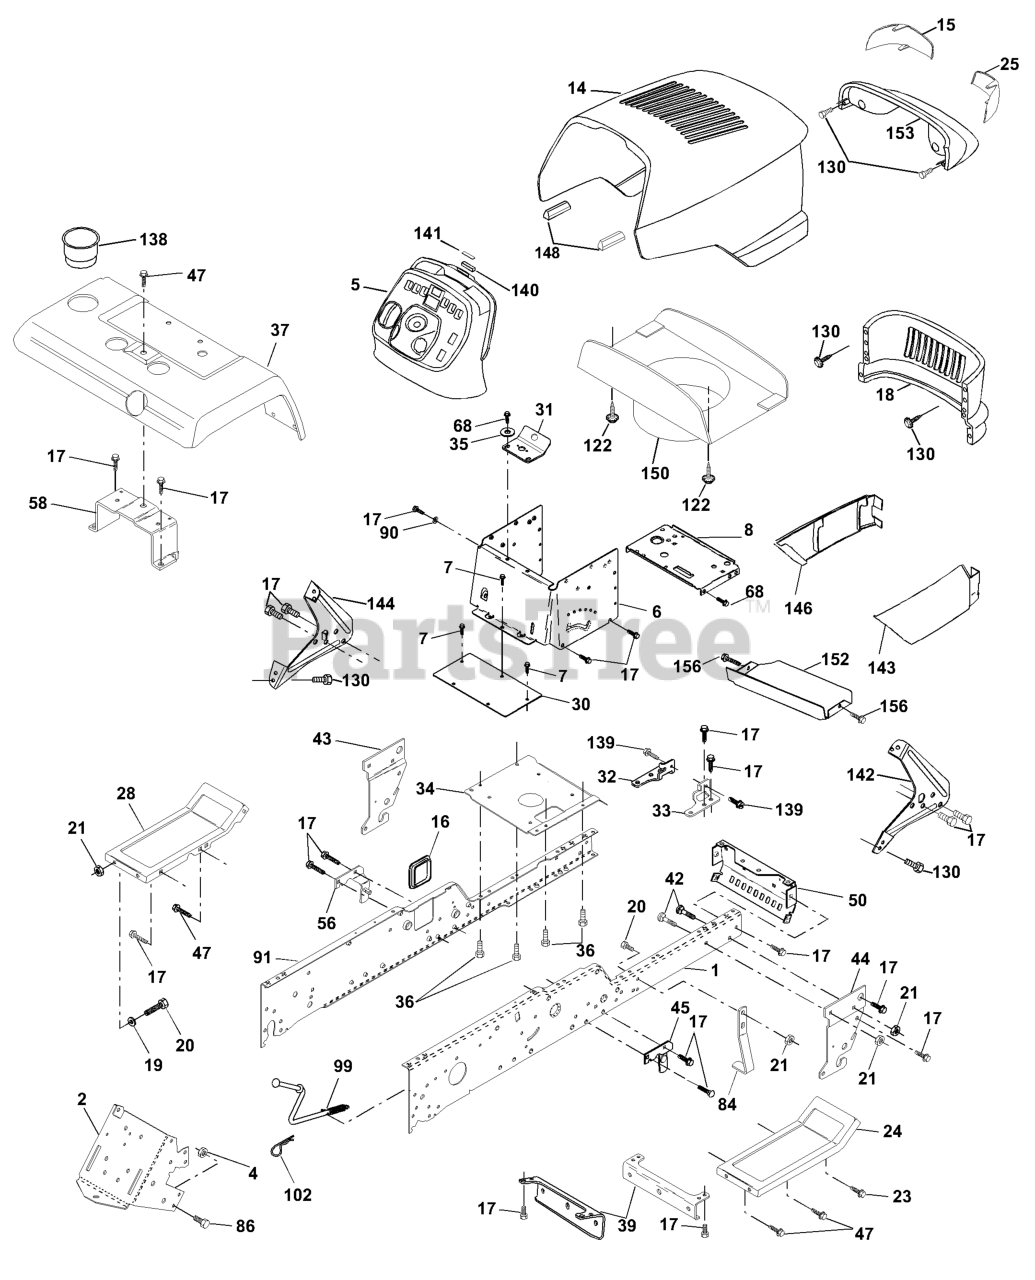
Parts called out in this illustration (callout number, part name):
1	RAIL, FRAME RH
2	DRAWBAR, GT
4	Nut, Lock Hex 7/16 Unc
5	DASH.STEALTH.YTGT.2CYL.BLK
6	DASH VGT, LOWER
7	SCREW
8	SUPPORT, BATTERY
14	HOOD ASM.
15	LENS RH
16	COVER ACCESS
17	SCREW 3/8-16X3/4
18	GRILLE
19	WASHER
20	BOLT
23	SCREW THDROL 3/8-16 X 1-1/2
24	FOOTREST RH
25	LENS LH
28	FOOT REST LH
30	SADDLE.HYDRO.95
31	BRACKET SUPT 1-PC VGT STEERING
34	PLATE ASM ENG CHASSIS
35	WASHER
36	SCREW 5/16"
37	FENDER
39	BRACKET AXLE, FRONT
42	BOLT D
43	FRONT SUSPENSION BRKT LH
44	FRONT SUSPENSION BRKT RH
45	BRACKET SUSP RH
47	SCREW 3/8-16X1/2
50	BRACKET, CHASSIS FRONT
56	BRACKET ASM, SUSP CHASSIS
58	BRACKET ASM, FENDER
68	Screw, 5/16-18 x 1/2
84	MOWER STOP
86	BOLT
90	LOCKWASHER
91	RAIL, FRAME LH
99	ROD ASM, BYPASS
102	RETAINER M
122	SCREW.HEX.WS.HD.8-18 X 7/8
130	SCREW
138	CUPHOLDER
139	BOLT, SHOULDER 5/16-18
140	MAGNET STEALTH
141	STRIKER PLATE
142	BRACKET DASH STEALTH(R)
143	SKIRT GRILLE RH
144	BRACKET DASH STEALTH LH
146	SKIRT GRILLE LH
148	EXTRUSION BUMPER (3 2) (2 2)
150	DUCT HEAT HOOD
153	LENS, HEADLIGHT BAR
